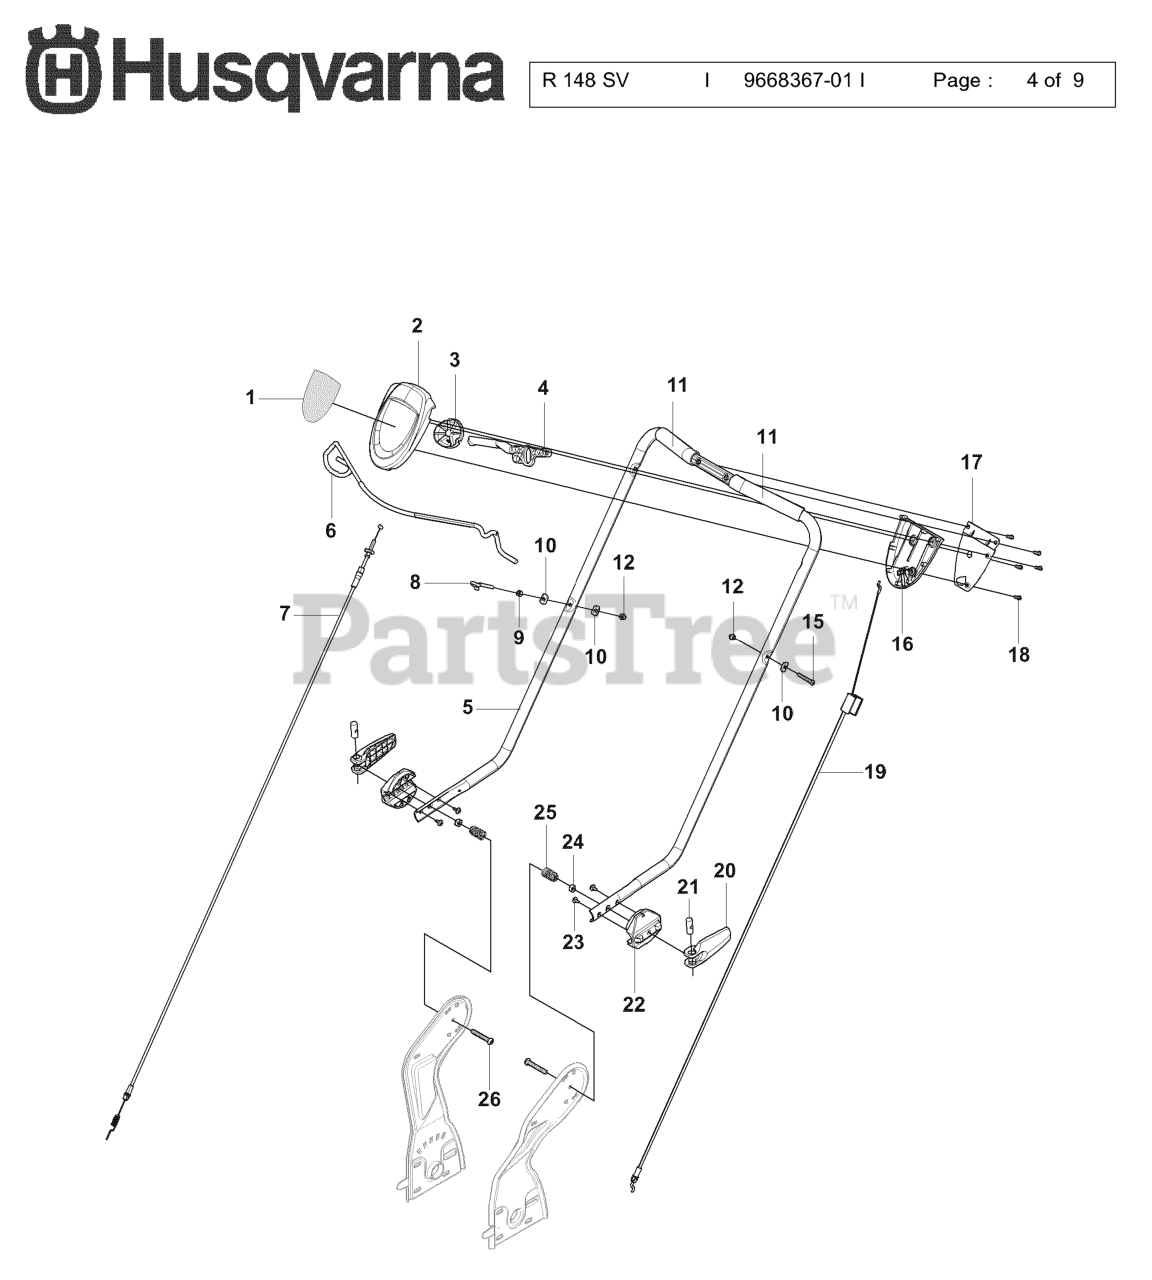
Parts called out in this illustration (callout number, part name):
2	COVER, DRIVE CONTROL BOTTOM
3	PULLEY.CAM.DRIVE.CONTROL.EZ
4	LEVER, DRIVE CONTROL
16	COVER, DRIVE CONTROL, TOP
17	BRACKET, DRIVE CONTROL
18	SCREW ITXPANT T50X16 ZN/FE (A
19	BRAKE WIRE
23	SCREW ITXPANTT M5X10 ZPB (A00
